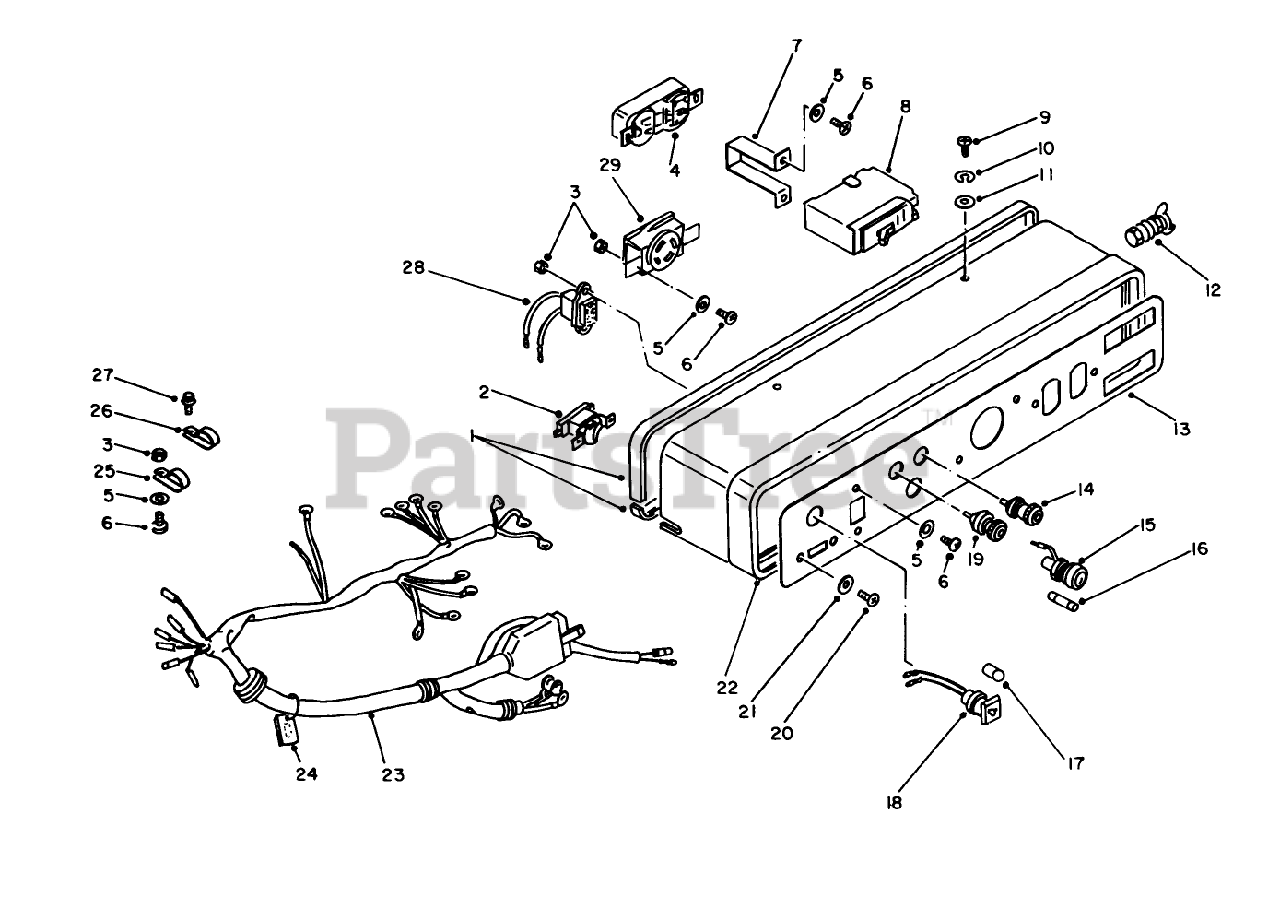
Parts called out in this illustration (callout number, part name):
2	Switch
4	Receptacle
5	Washer
6	Screw
7	Holder
8	Circuit Breaker
9	SCREW
10	Washer
11	WASHER
12	Terminal
13	PANEL PLATE
14	Terminal
15	Fuse Holder (Incl.Ref.#16)
18	Lamp (Incl.Ref.#19)
19	TERMINAL (-)
20	SCREW
21	Washer
22	Control Panel
23	Wire Harness
24	Fuse-Spare
25	CLAMP
26	Clamp
27	SCREW-HHF
28	Hertz Meter
29	Receptacle
